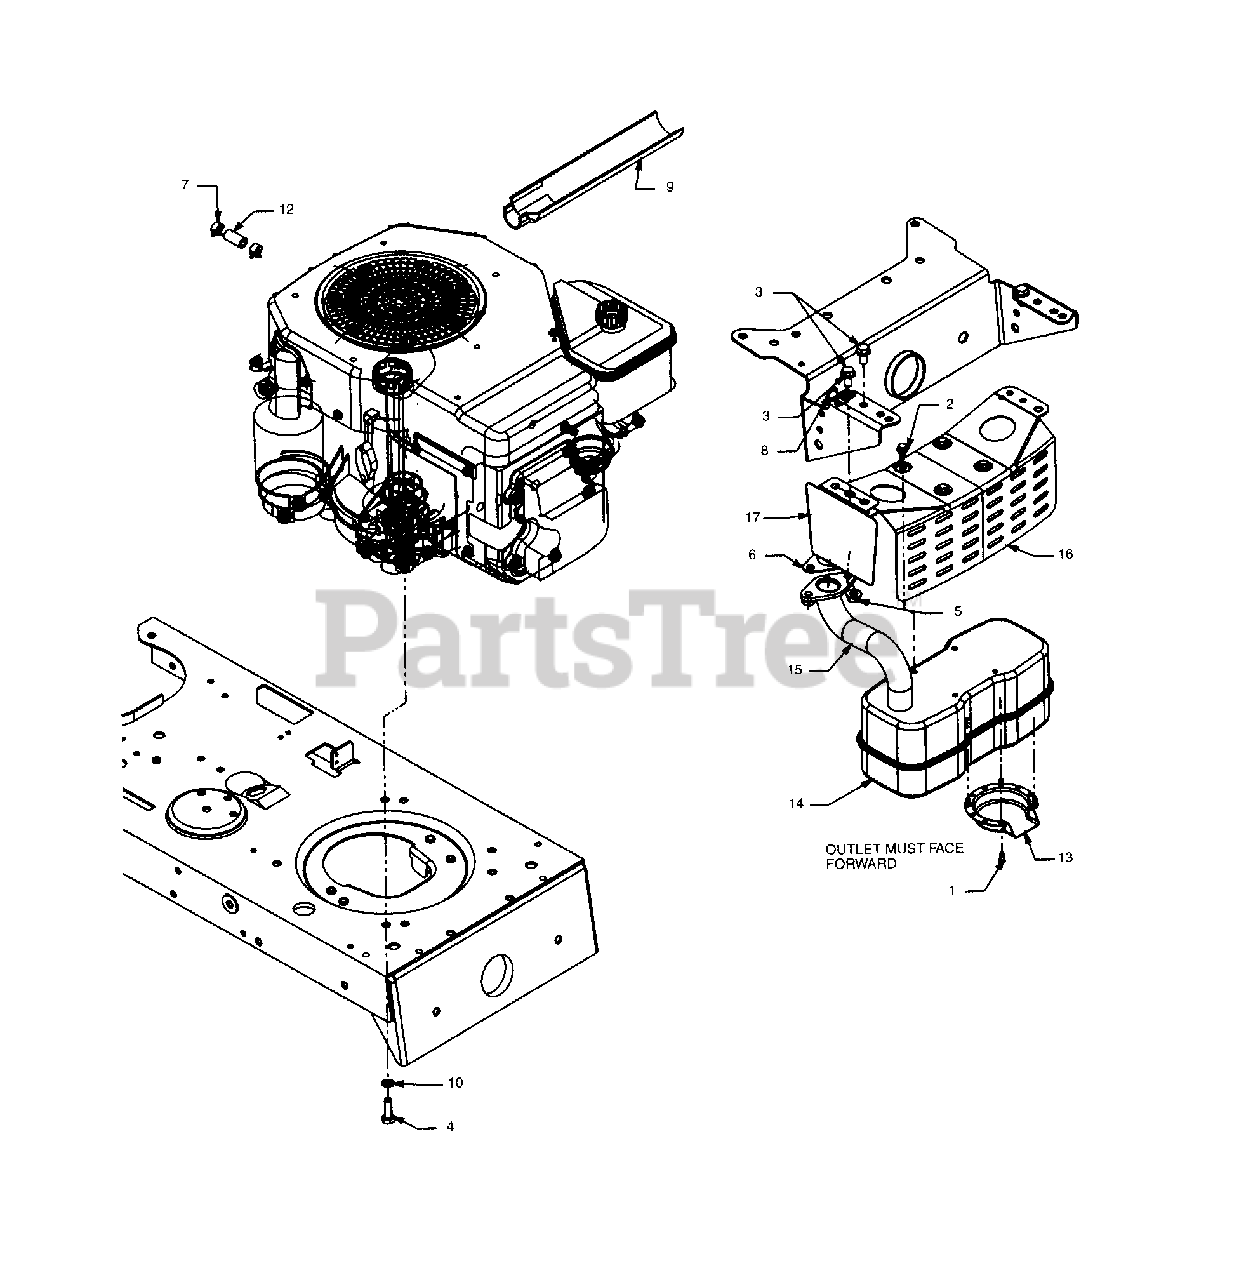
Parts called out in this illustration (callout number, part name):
1	Hex Tap Scr. #8-32 x .38" Lg.
2	Hex Wash. TT-Tap Scr. 1/4-20 x 5" Lg.
3	Hex Wash. TT-Tap Scr. 5/16-18 x .62" Lg.
4	Hex Bolt M8 x 1.25
5	Hex Flange Nut M8 Thd.
6	Exhaust Gasket
7	Hose Clamp
8	Clamp
9	Oil Drain Sleeve
10	External L-Wash. 5/16" I.D.
12	Fuel Line 12" Lg.
13	Muffler Deflector
14	Muffler
15	Exhaust Pipe
17	Shield Bracket.
